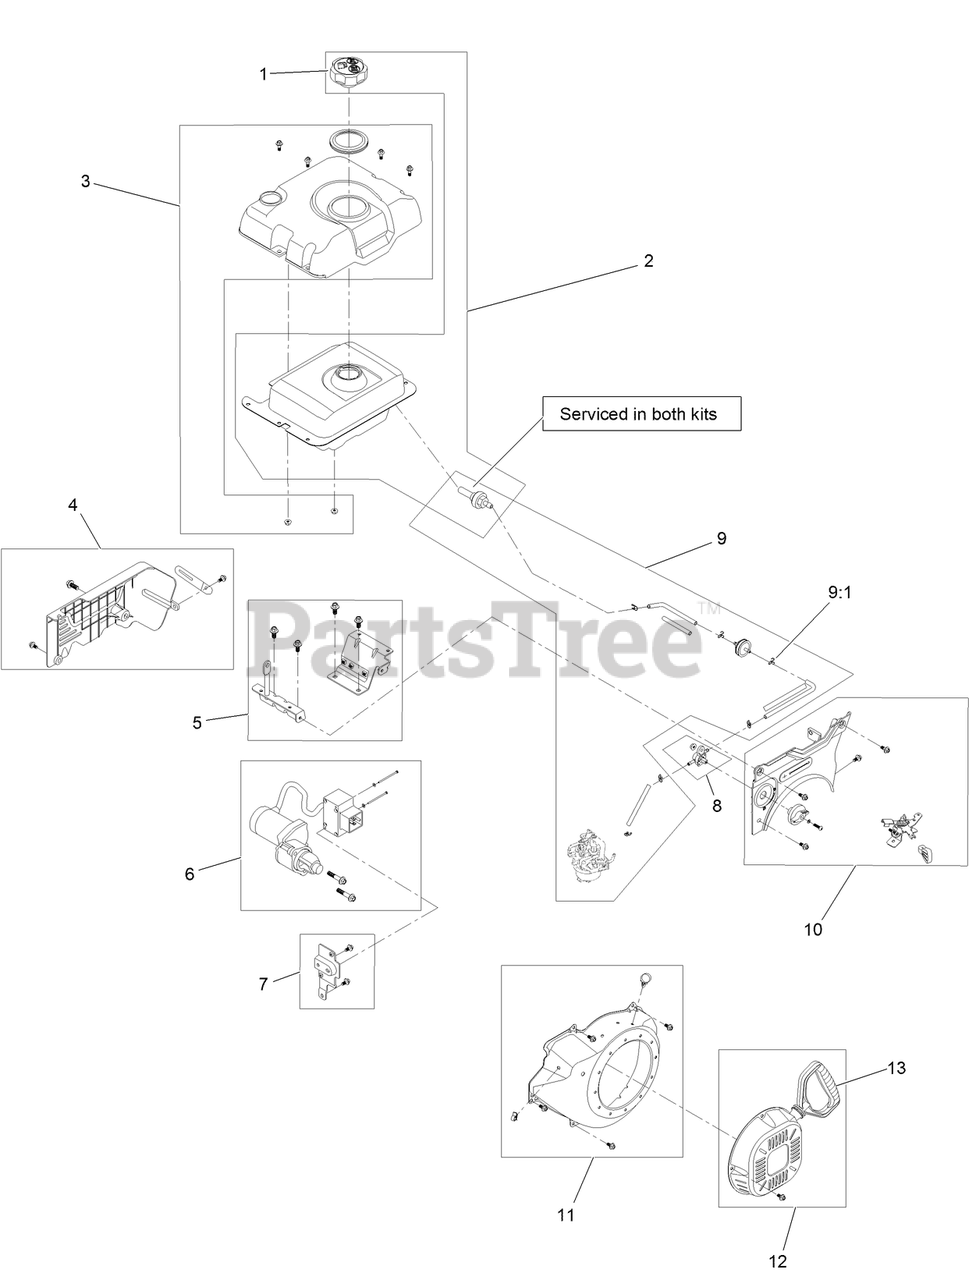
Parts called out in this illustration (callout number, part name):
1	CAP-FUEL
3	FUEL TANK COVER KIT
4	REAR PANEL AND HARDWARE KIT
5	TANK MOUNT BRACKET KIT
7	SWITCH BOX BRACKET KIT
8	FUEL SHUT-OFF VALVE KIT
9:1	CLAMP-HOSE
10	FRONT PANEL KIT
11	RECOIL SHROUD KIT
12	RECOIL KIT
13	HANDLE-RECOIL
